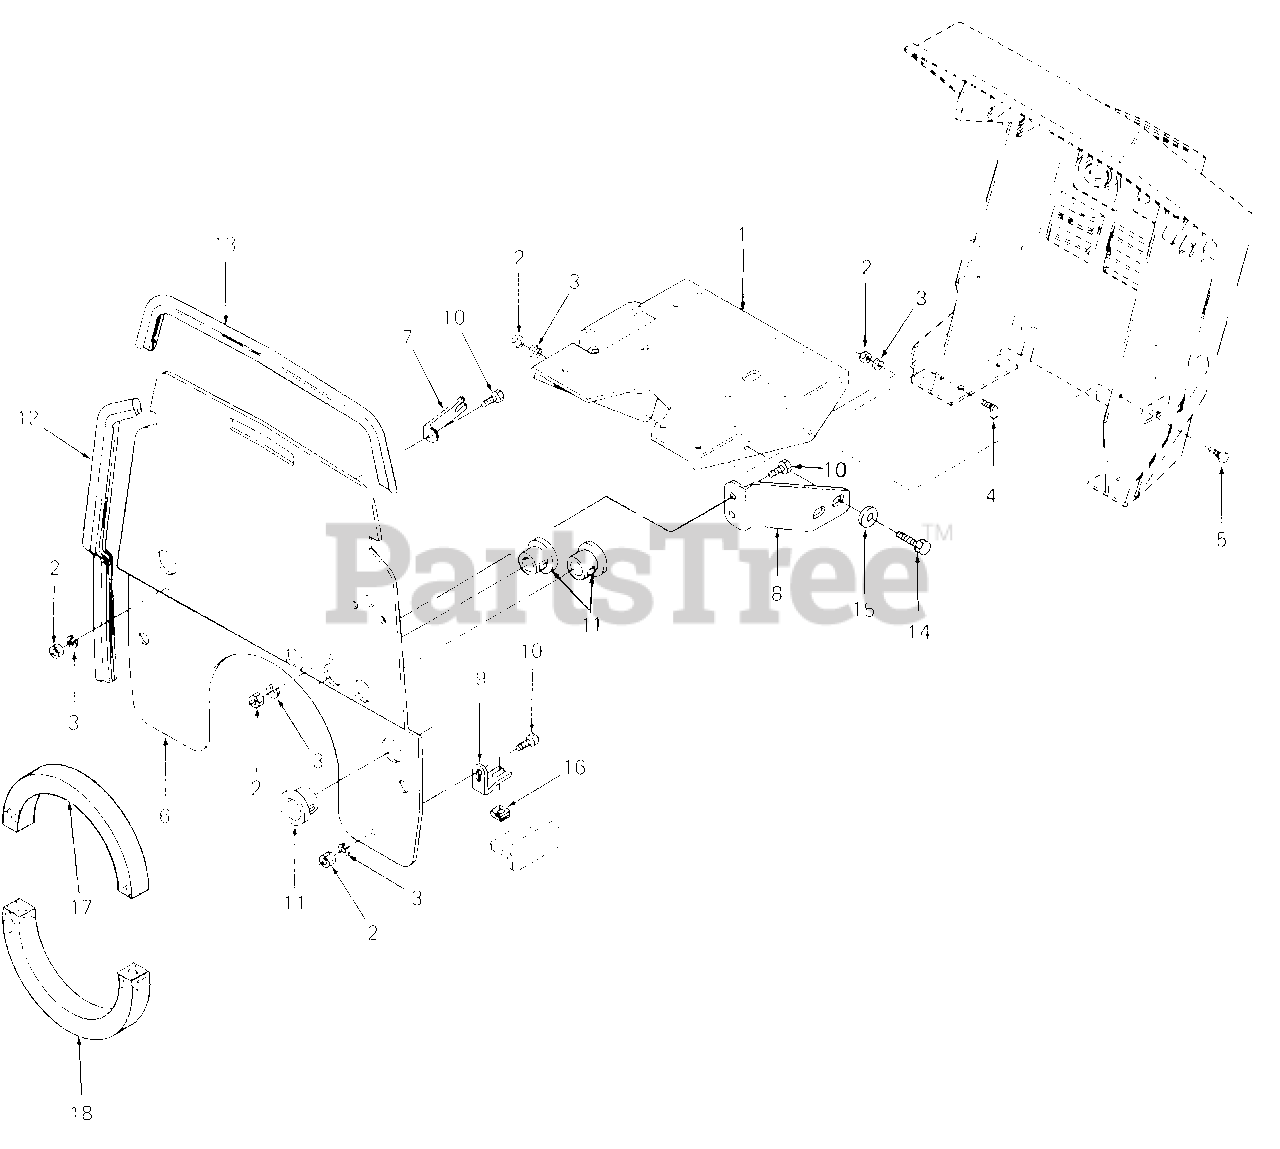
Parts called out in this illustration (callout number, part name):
1	Tray Assy, Battery
2	Nut, Hex, 1/4-20 GR5
3	Washer, Lock, 1/4
4	Bolt, J-Type, 1/4-20
5	Screw, Hex Cap, 1/4-20 X .62 Lg GR5
6	Baffle, Heat
7	L-Bracket, 1.9 Lg
8	L-Bracket, 5.0 Lg
9	L-Bracket
10	Screw, Hex Cap, 1/4-20 X .5 GR
11	Bushing, Snap, 7/8 ID
12	Seal, Heat Baffle, 19" Lg
13	Seal, Heat Baffle, 17" Lg
14	Screw, Hex Cap, 5/16-18 X .50 lg
15	Washer, Bell, .345 X.88 X .060 Thk
16	Nut, U-Type, 5/16-18
17	Strip, Foam Gasket Sealing, 17" Lg
18	Strip, Foam Gasket Sealing, 27" Lg
